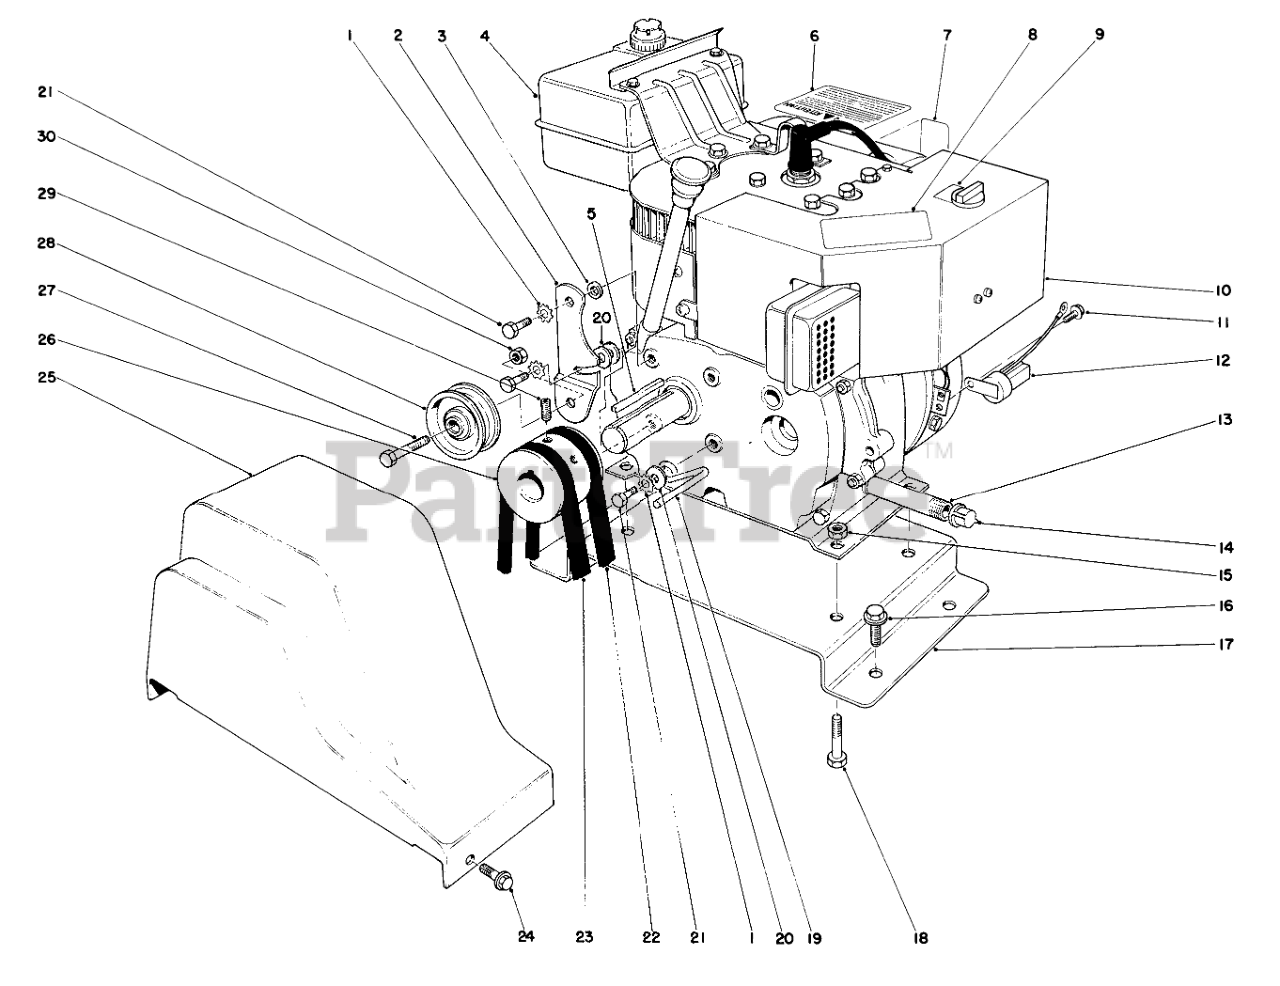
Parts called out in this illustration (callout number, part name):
1	WASHER-LOCK
2	ENGINE IDLER ARM
3	SPACER
4	GAS TANK 2 QT W CAP
6	Decal-Hazards Caution
7	DECAL-PRIMER
8	HOT SURFACE DECAL
9	CHOKE DECAL
11	SCREW-HWH
12	INTERLOCK MODULE
13	NIPPLE-PIPE
14	CAP-PIPE
15	NUT-LOCK, NI
16	SCREW-HWHTF
17	ENG MTG PLATE R
18	SCREW-HH
19	BELT RETAINER
20	WASHER-PLAIN
21	SCREW-HH
22	V-BELT
23	V-BELT
24	SCREW-HWH
25	BELT GUARD
26	ENGINE PULLEY
27	SCREW-HH
28	PULLEY-IDLER
29	SETSCREW
30	NUT-LOCK, NI
